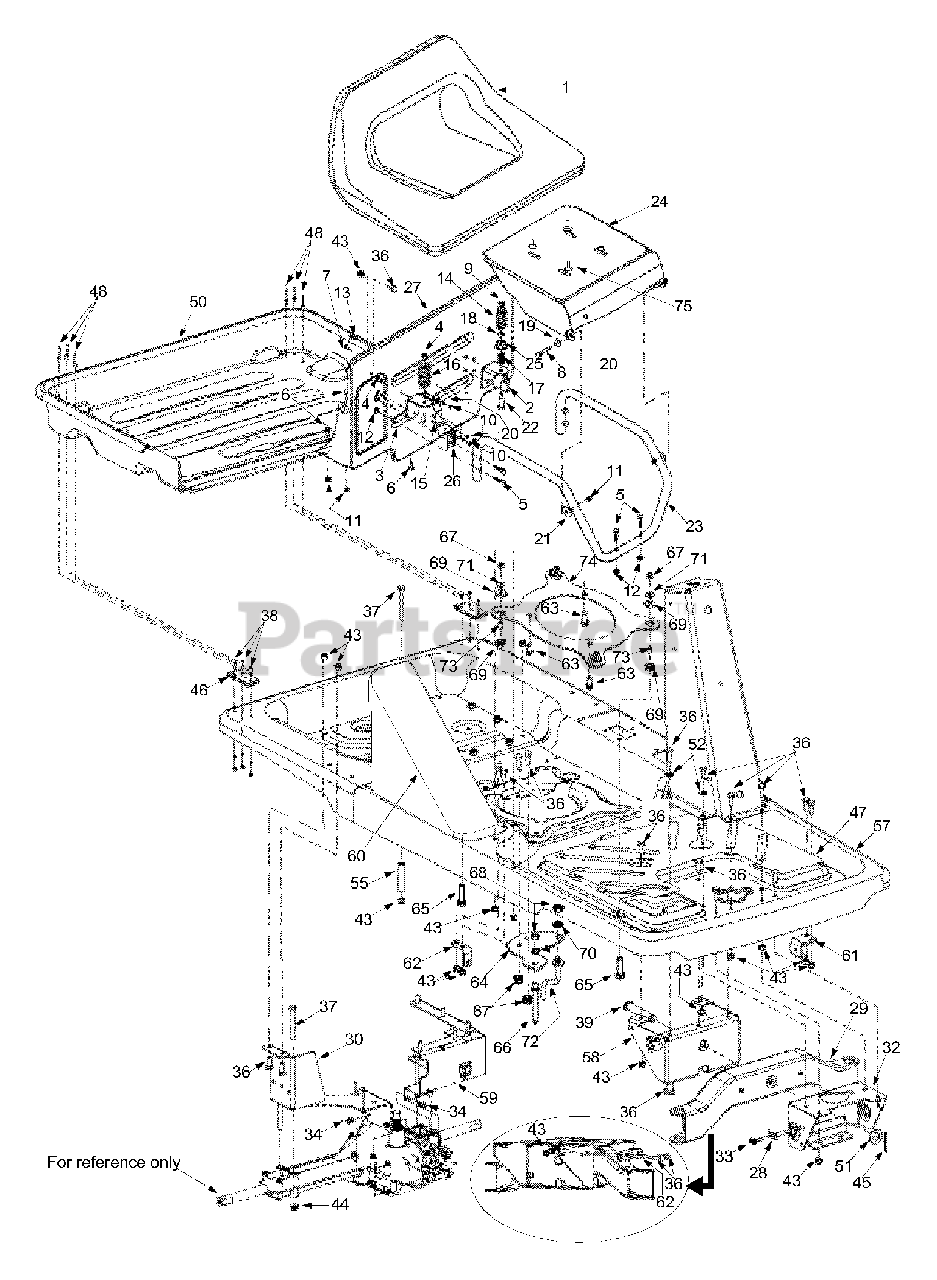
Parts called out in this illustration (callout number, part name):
1	Seat: Black, Low Back
5	Carriage Bolt 5/16 x 1.5"
6	Hex Bolt M8-1.25: 20
7	Special Screw M6-1: 16
8	Hex Bolt M8-1.25: 45
9	Flange Lock Nut 3/8-16
10	Hex Nut M6-1
11	Hex Lock Nut M8-1.25
12	Flange Lock Nut 5/16-18
13	Ratchet Clip
14	Compression Spring
15	Actuator Spring
16	Compression Spring
17	Compression Spring
18	Bell Washer .375 x .870 x .063
19	Shoulder Bushing
20	Lock Washer
21	Flat Washer 8.4 x 35
22	Shoulder Screw
28	Switch Plate
34	TT Screw 1/4-20 x 0.5"
36	Hex Screw M8-1.25: 20
37	Special Screw
38	Special Screw
39	Clevis Pin
43	Hex Lock Nut
44	Flange Lock Nut
45	Cotter Pin
47	Foot Pad
48	Rivet
50	Bag Tray
51	Flat Washer .64 x 1.24 x .06
52	Flat Washer 8.4 x 16
55	Spacer
62	Cable Bracket
63	TT Sems Screw 3/8-16 x 1.0
64	Belt Keeper Bracket
65	Hex Bolt M8-1.25: 30
66	Pin: Belt Guard
67	Lock Nut M8-1.25
68	Hex Nut 5/16-18
69	Engine Mount: Gromm.
70	Lock Washer 5/16
71	Flat Washer 8.4 x 24
72	Belt Keeper Rod
73	Spacer
